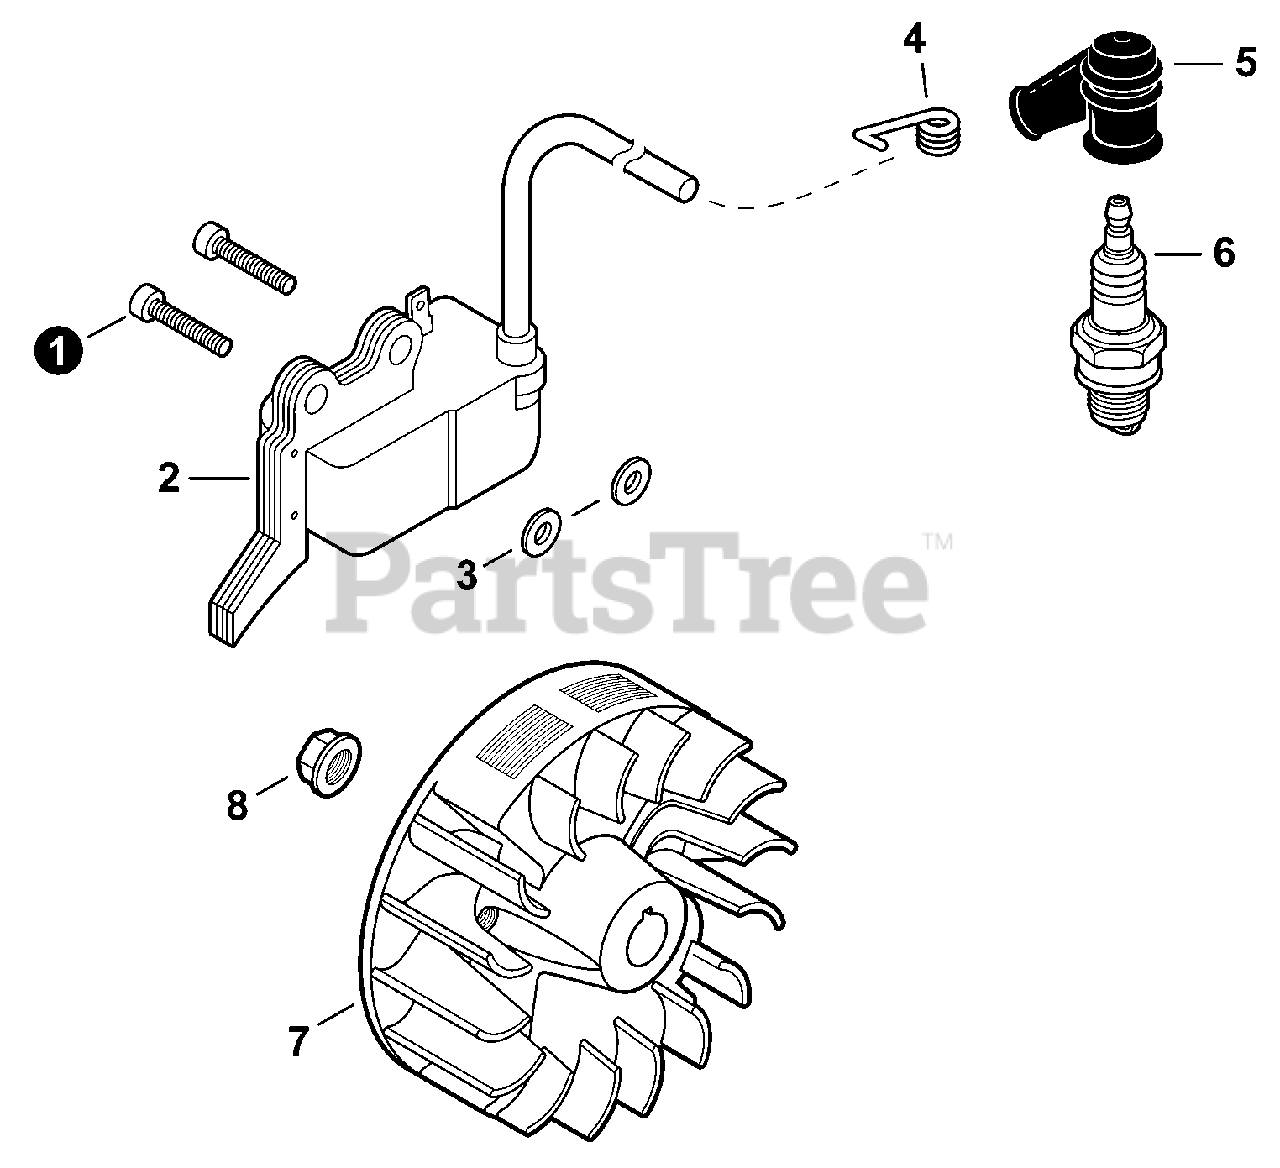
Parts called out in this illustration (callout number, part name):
1	BOLT, TORX 5×20
2	COIL, IGNITION
3	SPACER 5
4	TERMINAL, SPARK PLUG
5	CAP, SPARK PLUG
6	SPARK PLUG - BPMR8Y
7	FLYWHEEL
8	NUT, FLANGE M8
